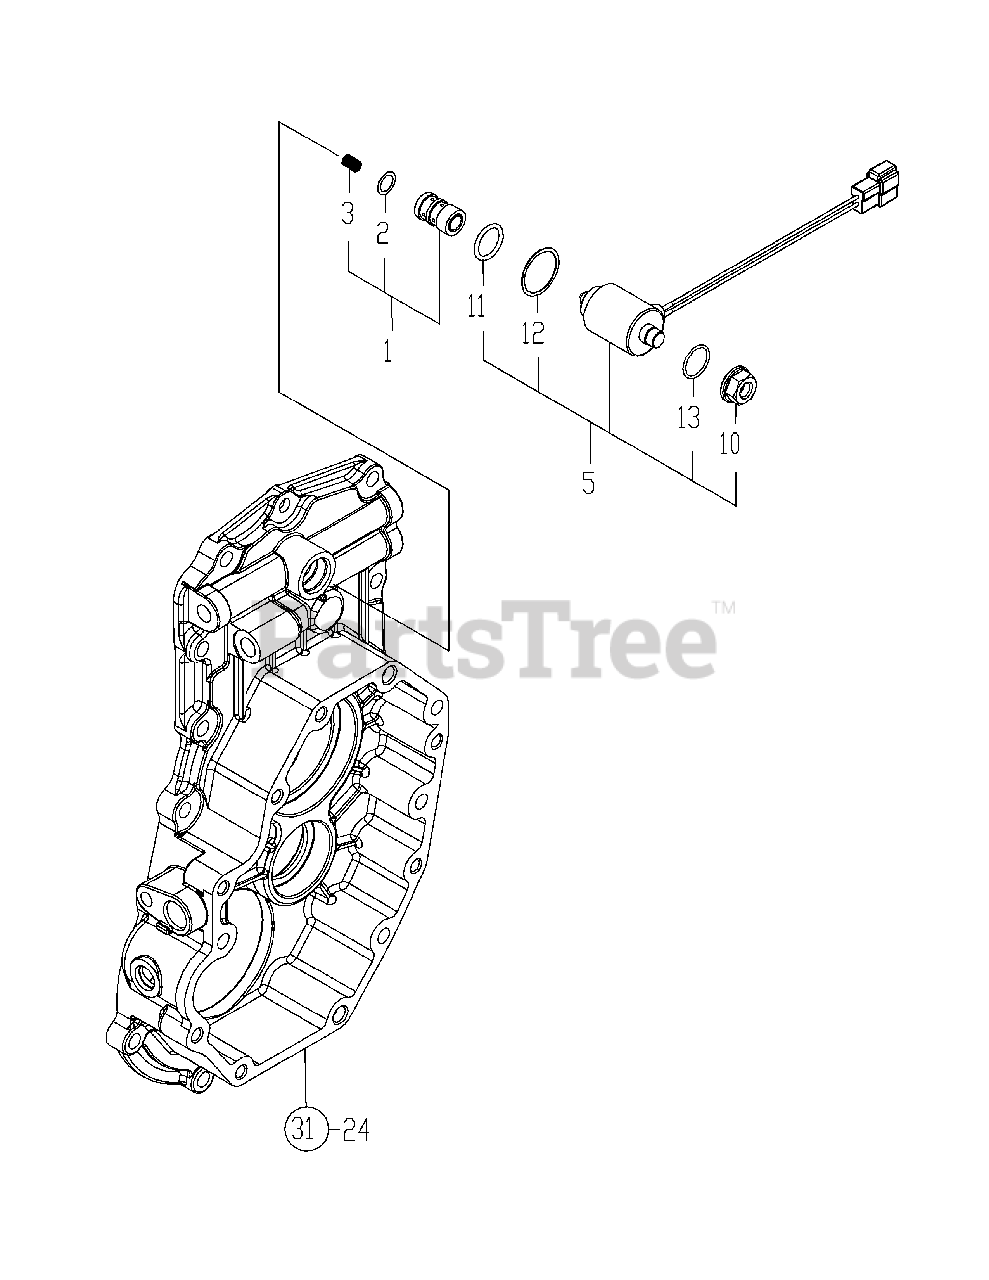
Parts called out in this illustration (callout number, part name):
1	VALVE ASSY, SOLENOID
3	SPRING, SOLENOID
11	PACKING, P 18.0
12	GASKET, SOLENOID
13	PACKING, S 11.2
